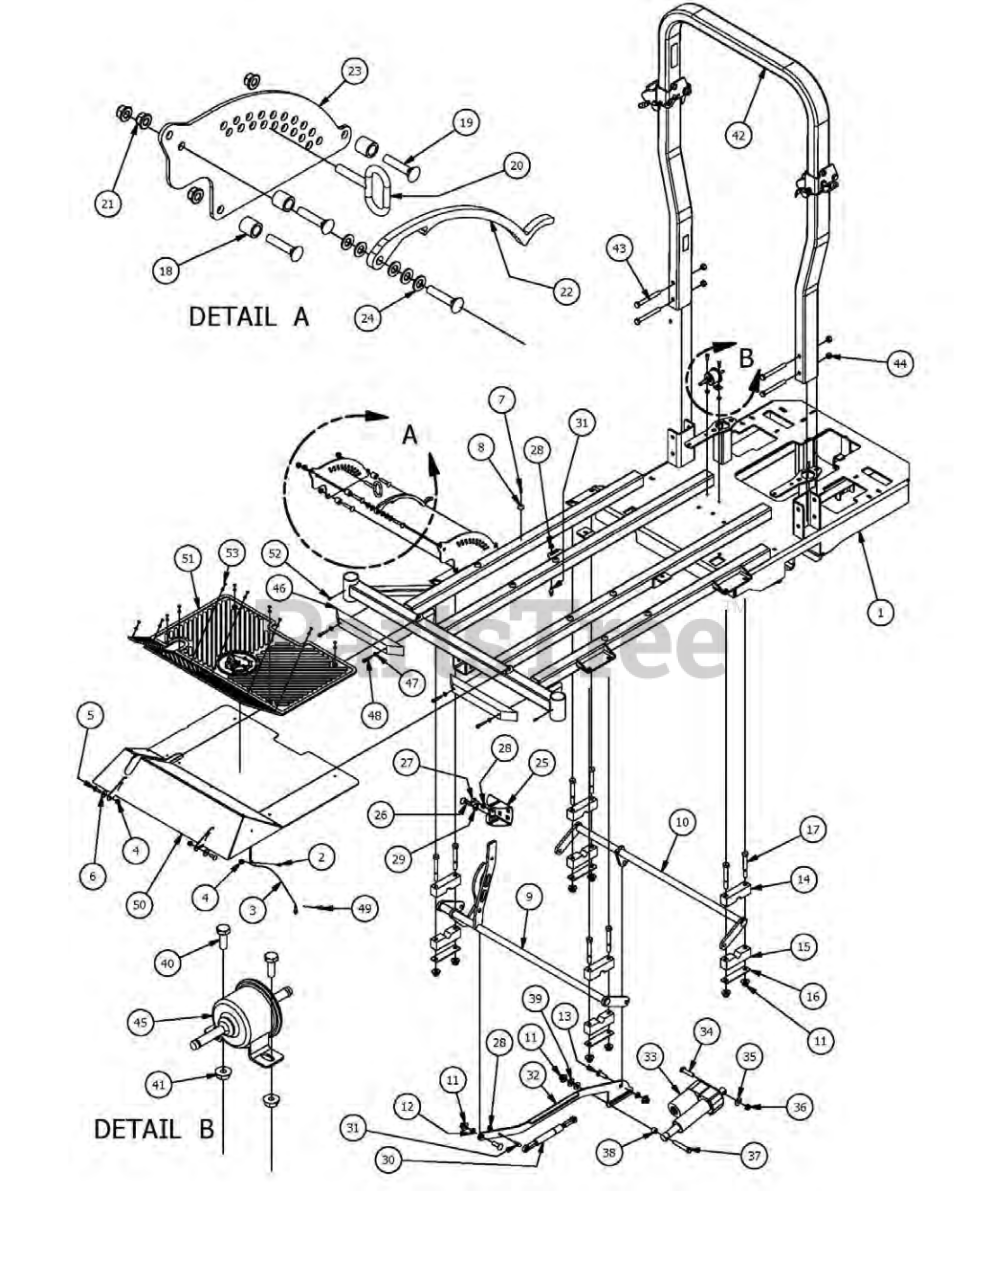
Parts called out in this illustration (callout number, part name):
1	Outlaw Diesel Frame 2012
2	1/4" x 5/8" BS C/S 18-8 SS
3	Floor board Cable W/ Swivel Ends
4	5/16" Nylock Flange Nut Zinc
5	5/16" x 1" Carriage Bolt
6	360 ID Plastic Washer
7	#10 x 1/2" Self Tapping Screw
8	Button Bumper
9	2015 Outlaw Act Bar Assembly (Front)
10	2015 Outlaw Act Bar Assembly (Rear)
11	1/2-13 Nylon Flange Nut
12	Bushing- SF-1620-4
13	1/2 x 1-1/2 Carriage Bolt
14	Two Piece Pillow Block (Male)
15	Two Piece Pillow Block (Female)
16	Two Piece Pillow Block Strap
17	1/2" x 4" Bolt (Grade 8)
18	Spacer 3/4 OD x 1/2 ID x 3/4 Length
19	3/8 x 1 3/4 Carriage Bolt
20	Deck height lever pin
21	3/8" Nylock Flange Nut
22	Outlaw Deck Lever Lock
23	Outlaw Height Indicator Plate (Outer)
24	390x.750 x .062 Nylon Washer
25	Outlaw Deck Lift Pedal
27	5/16-18 x1 Thumb Screw Zinc
28	5/16" Flange Nut
29	1/2" Hex Nut
30	250lb Gas Spring
31	10mm Damper Ball Stud-Steering
32	Outlaw Linkage Bar Susp Frame
34	1/2-13x2 Grade 8 Hex Bolt
35	1/2" Washer (Grade 8)
36	1/2" Nylcock Nut (1/2 Jam)
37	1/2" x 3" Hex Bolt
38	1/2 x 1/2 Spacer
39	.505 Nylon Spacer
40	1/4" x 3/4" Hex Bolt
41	1/4-20 Hex Flange Nuts Zinc w/Serrations
42	2014 & Newer Diesel 2x3 Folding ROPS
43	1/2" x 4 1/2" Bolt.
44	1/2" Center Lock Nut
45	Electric Fuel Pump
46	14" Rubber Bumper
47	1/4" Flat Washer
48	1/4" x 1 1/2" Self Tapping Screw
49	1/4 x 1 Hex Head tek screw
50	2016 Outlaw Floor Panel
51	2016 Outlaw Floor Mat
52	1/4" Press in Grease Fitting
53	Ratchet Fastener-2016 Floorboard
